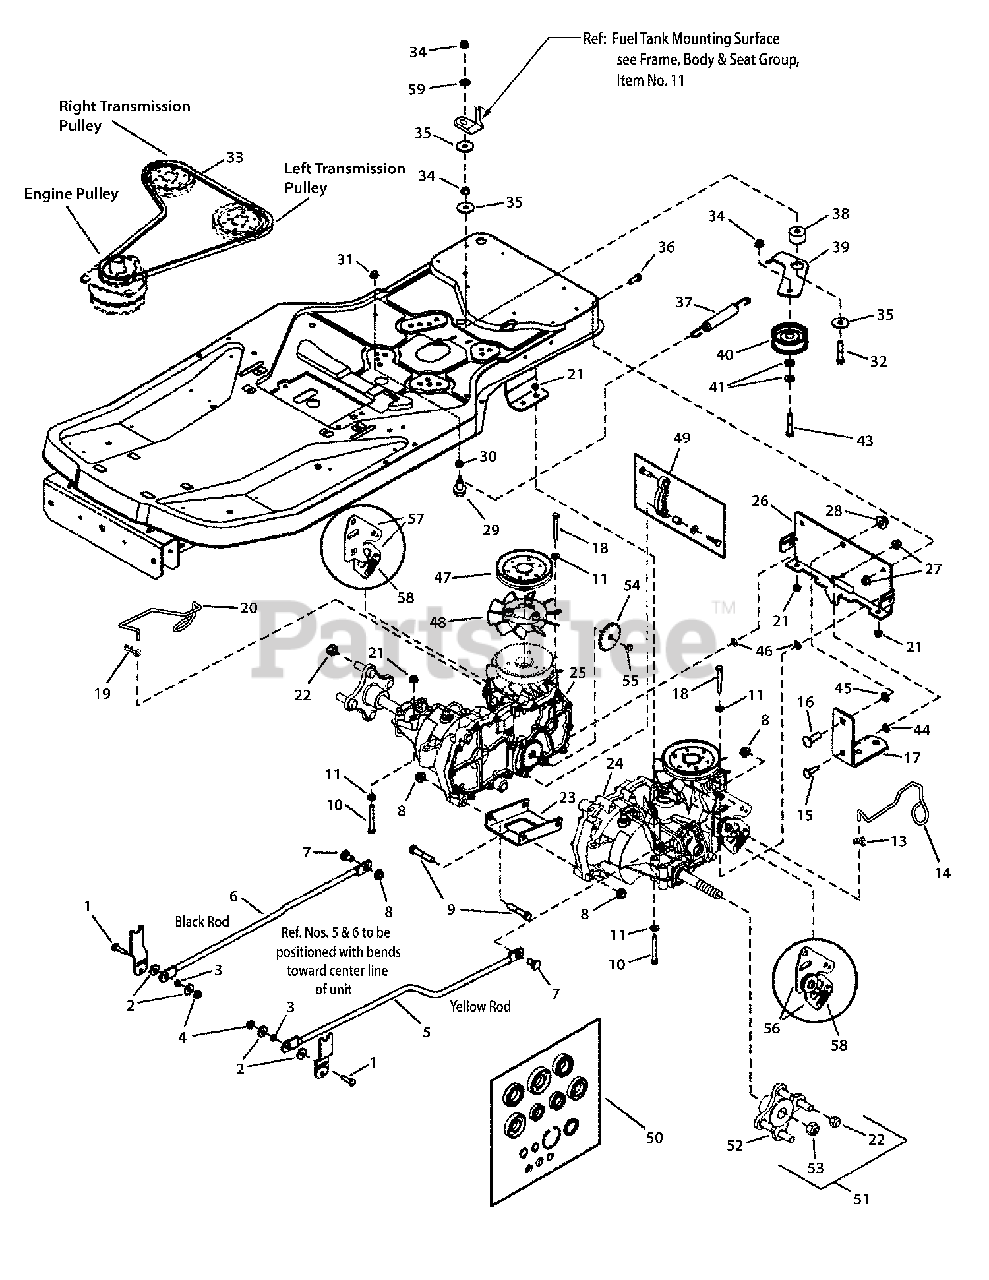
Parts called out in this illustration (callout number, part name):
1	BOLT, 5/16-18 x 1-1/4" Round Head Short Square Neck GR5, Black
2	WASHER, 5/16" Flat (.341 I.D. x 1.00 O.D. x .13 Thick) Black
3	SPACER, .323 I.D. x .500 O.D. x 0.270 Long Heat Treated
4	NUT, 5/16-18 Hex Keps Conical Washer, Black
5	ROD, Control, LH (.500 Dia. X 27.88 Long)
6	ROD, Control, RH (.500 Dia. X 27.88 Long)
7	SHOULDER BOLT, 7/16-14 x 1.07 Long, GR5
8	NUT, 7/16-14 Hex Flange Lock Two Way, Black
9	SCREW, 7/16-14 x 2-1/4" Hex Head Cap, GR8, Black
10	SCREW, 5/16-18 x 2-3/4" Hex Head Cap, GR5, Black
11	WASHER, .312 (.34 I.D. x.75 O.D.)
13	CLIP, Rod End Clevis RH (for .188 Dia. Rod)
14	ROD, Tow Valve LH (.156 Dia. 5.05 Long)
15	BOLT, 3/8-16 x 1-1/4" Round Head Short Square Neck, Black
16	BOLT, 1/2-13 x 1-1/2" Round Head Short Square Neck, GR5, Black
17	DRAWBAR, .250 Thick - Black
18	SCREW, 5/16-18 x 2-1/2" Hex Head Cap, GR5, Black
19	CLIP, Rod End Clevis LH (for .188 Dia. Rod)
20	ROD, Tow Valve RH (.156 Dia. 5.05 Long)
21	NUT, 5/16-18 Hex Flange Lock, Small - Black
22	NUT, 1/2-20, (for Wheel Bolt) Silver
23	SUPPORT, Transmission Center - Black
24	TRANSMISSION, Hydro Gear EZT LH (ZC-AHBB-2A7B-1DPX)
25	TRANSMISSION, Hydro Gear EZT RH (ZC-DHBB-2A7C-1DPX)
26	SUPPORT, Transmission Rear - Black
27	NUT, 3/8-16 Hex Flange Nyloc
28	NUT, 1/2-13 HEX NYLOCK FLANGE
29	SHOULDER BOLT, 5/16-18 GR5
30	WASHER, 5/16 Flat (.341 I.D. x .87 O.D. X .06 Thick) Black
31	NUT, 5/16-18 Hex Flange Lock Large, Black
32	SCREW, 3/8-16 x 2-1/2 Hex Head Cap, GR 5
33	* V-BELT, Transmission Drive (HA Sect. 54.40 Effective Length)
34	NUT, 3/8-16 Hex Flange Lock Two Way, Black
35	WASHER
36	SCREW, 3/8-16 x 1" Hex Head Cap, GR5, Black
37	SPRING, Extension
38	SPACER, .387 I.D. x 1.50 O.D. x 1.04 Long (Powdered Metal) Yellow
39	ARM, Idler (Transmission Drive) Black
40	PULLEY, Idler
41	WASHER, .375 Flat (.41 I.D. x .87 O.D.)
43	SCREW, 3/8-16 x 2" Hex Head Cap, GR5
44	NUT, Push Pal, 3/8"
45	NUT, Push Pal, 1/2"
46	NUT, Push Pal .312 Dia. Thread .625 O.D., Black
47	PULLEY, 4-1/2" Transmission
48	FAN, 6" Transmission
49	BRAKE ARM & PIN, Hydro-Gear
50	KIT, Hydro Seal
51	KIT, Hub Replacement (includes one Hub & one Axle Nut)
54	GEAR, Parking Brake, Transmission
55	CLIP, E Transmission Parking Brake
56	KIT, L.H. Control Arm
57	KIT, R.H. Control Arm
58	SPRING, Extension (Used on Hydro-Gear P/N ZC-AHBB-2A7B-1DPX and ZC-AHBB-2A7B-1DPX)
59	WASHER, Flat, .406X1.25X.132 ZP
